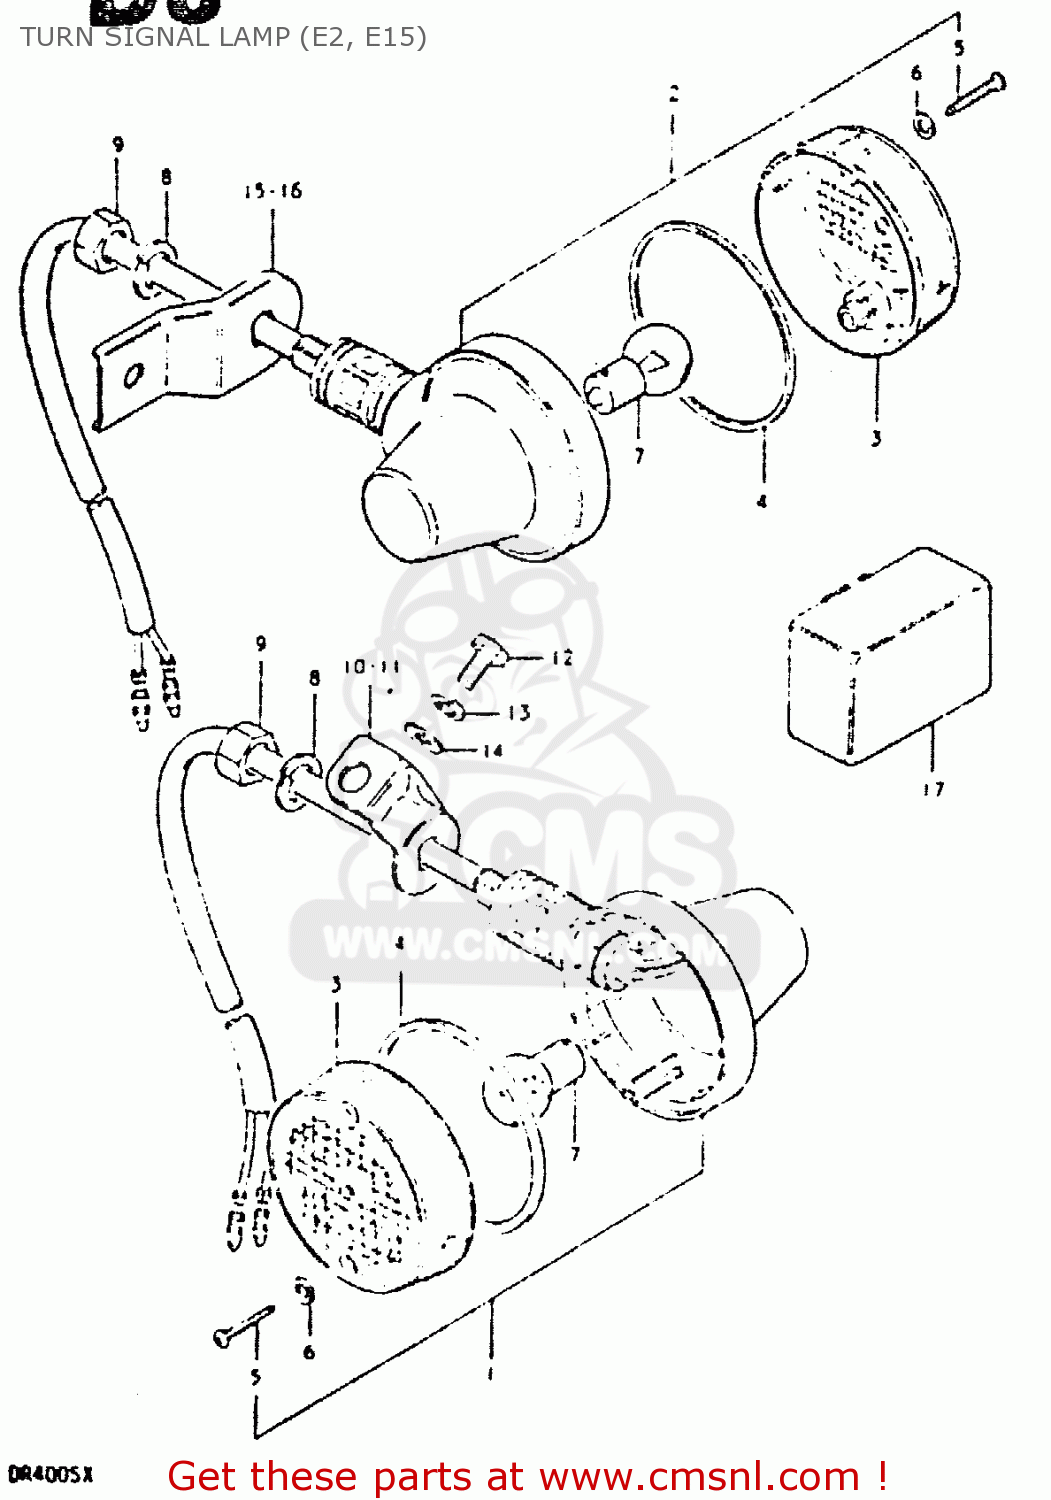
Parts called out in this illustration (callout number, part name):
1	LAMP ASSY,RR TURNSIGNAL
2	LAMP ASSY,RR TURNSIGNAL
3	LENS
4	GASKET (NAS)
5	SCREW TAPP.
6	GASKET (NAS)
7	BULB (6V,18W)
8	WASHER,LOCK 12
9	NUT
10	BRACKET,TURN SIGNAL LAMP
11	BRACKET,TURN SIGNAL LAMP
12	BOLT
13	LOCK WASHER
14	WASHER
15	BRACKET, REAR RH
16	BRACKET, REAR LH
17	RELAY,TURN SIGNAL
